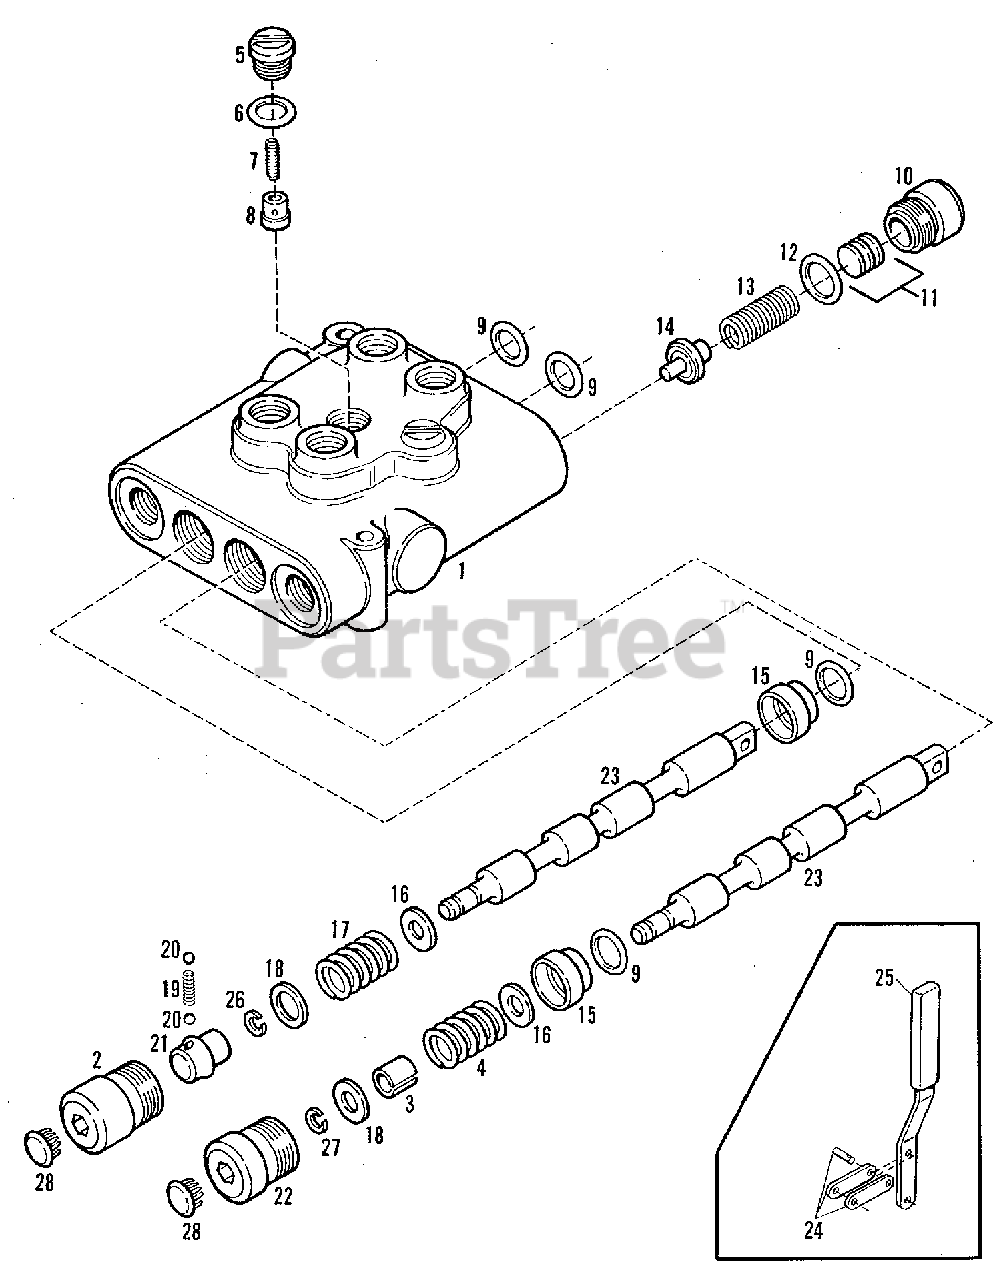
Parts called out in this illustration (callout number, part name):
1	BODY, Valve
3	SPACER, Spool
4	SPRING, Spool Centering
5	PLUG ASSEMBLY, Lift Check
6	O-RING, Plug Assembly
7	SPRING, Lift Check Plug
8	PLUNGER, Lift Check Plug
9	O-RING, Spool
10	PLUG ASSEMBLY, Relief Valve
11	SHIM, Relief Valve (.015 Thick)
11	SHIM, Relief Valve (.010 Thick)
11	SHIM, Relief Valve (.035 Thick)
12	O-RING, Relief Valve Plug
13	SPRING, Relief Valve
14	POPPET, Relief Valve
15	BUSHING, Spool
16	WASHER, Spool (.020 Thick)
16	WASHER, Spool (.046 Thick)
17	SPRING, Spool Centering
18	WASHER, Spool (.046 Thick)
18	WASHER, Spool (.065 Thick)
19	SPRING, Detent
20	BALL, Detent Spring, 5/32 Diameter
21	CAP, Detent Adapter
22	CAP, Detent
23	SPOOL
24	LINK ASSEMBLY, Valve
25	HANDLE ASSEMBLY, Valve
25	PIN, Cotter, 3/16 x 2
26	RING, Retainer (5/16 Round Open)
27	RING, Retainer (Square - 5/16 Closed)
28	BUTTON, Insert
